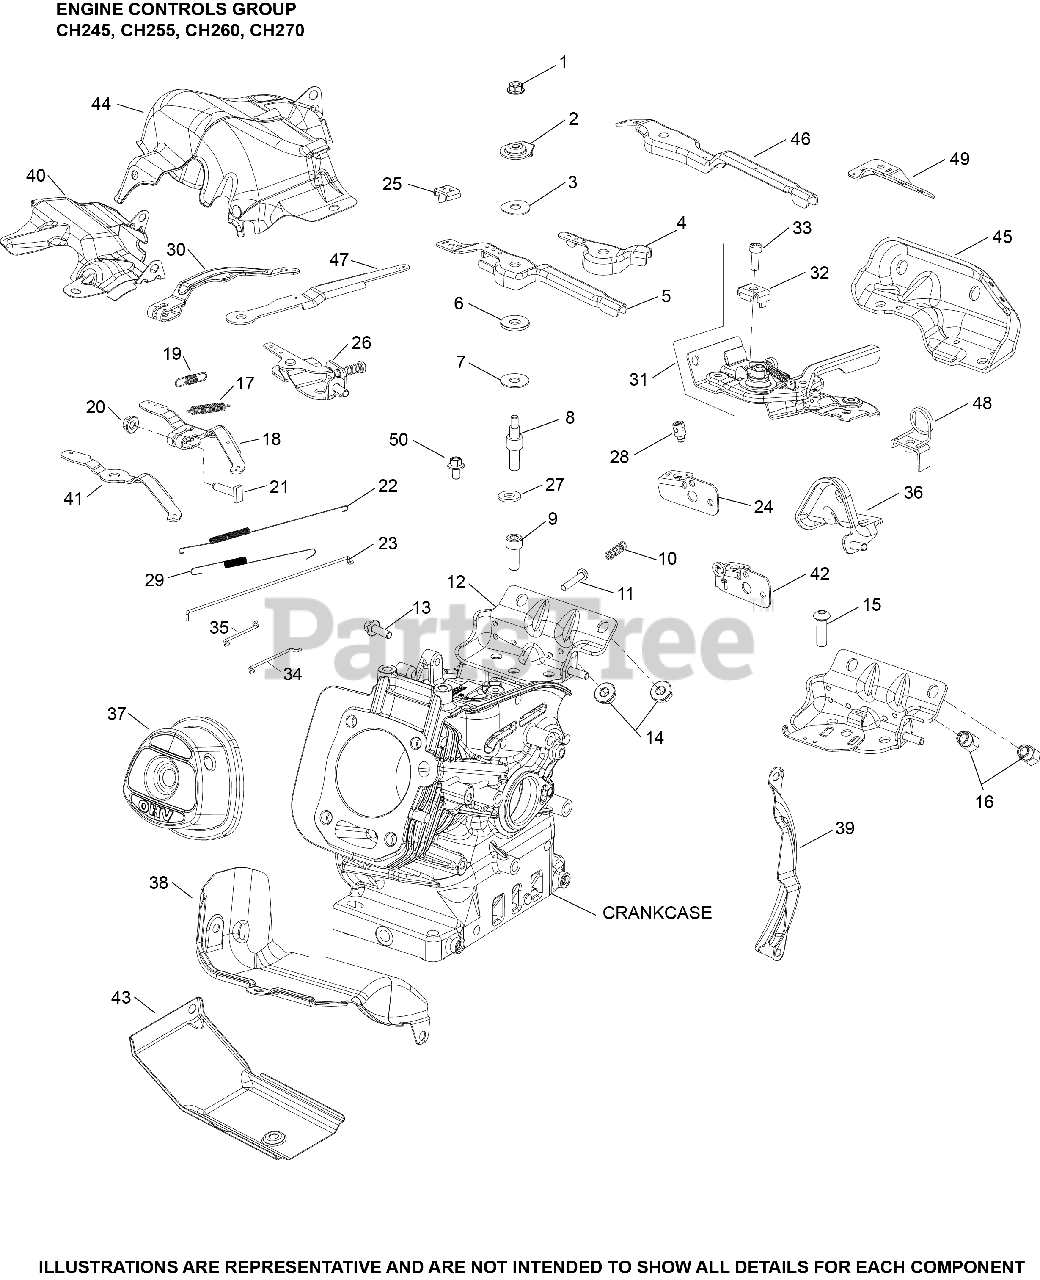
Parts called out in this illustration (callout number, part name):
1	NUT, HEX FLANGE LOCK (M6)
10	SPRING, COMPRESSION
13	SCREW, M6 X18
18	KIT, GOVERNOR LEVER
19	SPRING, GOVERNOR
20	NUT, HEX FLANGE (M6) - USE 14 100 16-S
21	SCREW, RECTANGLE HEAD (M6)
22	SPRING, LINKAGE
23	LINKAGE, GOVERNOR
1753609-S	CONTROL ASSEMBLY, FIXED SPEED
25086652-S	SCREW SPEED ADJUSTING
